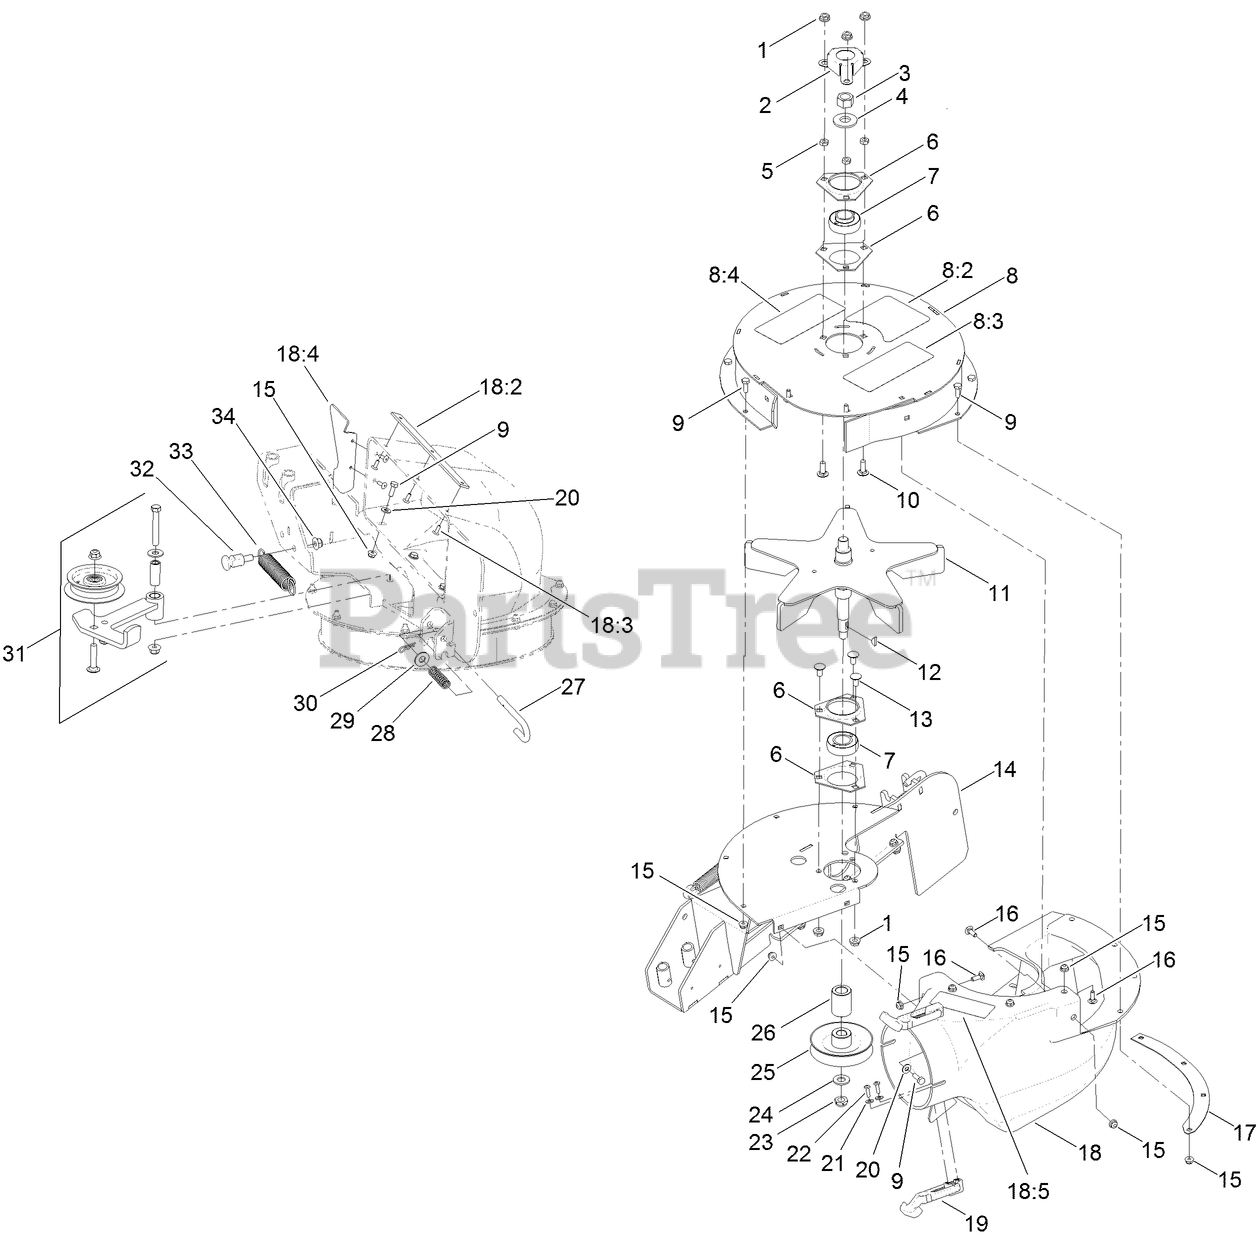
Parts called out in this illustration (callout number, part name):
1	NUT-HF
2	COVER-NUT
3	NUT-HEX
4	WASHER-SPRING
5	NUT-JAM
6	HOUSING-FLANGE
7	BEARING
8	UPPER HOUSING ASM
8:2	DECAL-WARNING
8:4	DECAL-WARNING
9	SCREW-HH
10	BOLT-CARR
11	IMPELLER
12	KEY-WOODRUFF
13	SCREW-CARR
14	FRAME-BLOWER
15	NUT-HF
16	BOLT-CARR
17	PLATE-BACKING
18	BLOWER CHUTE ASM
18:2	Plate-Reinforcing
18:3	RIVET-BLIND
18:4	PLATE-FILLER
18:5	DECAL-WARNING
19	LATCH-RUBBER
20	WASHER-FLAT
21	WASHER-FLAT
22	SCREW-PPH
23	NUT-LOCK, NI
24	WASHER-FLAT
25	PULLEY
26	SPACER
27	PIN-LATCH
28	SPRING-COMPRESSION
29	WASHER-FLAT
30	PIN-COTTER
31	IDLER ARM ASM
32	ANCHOR-SPRING
33	SPRING-EXTENSION
34	NUT-HF, NI
